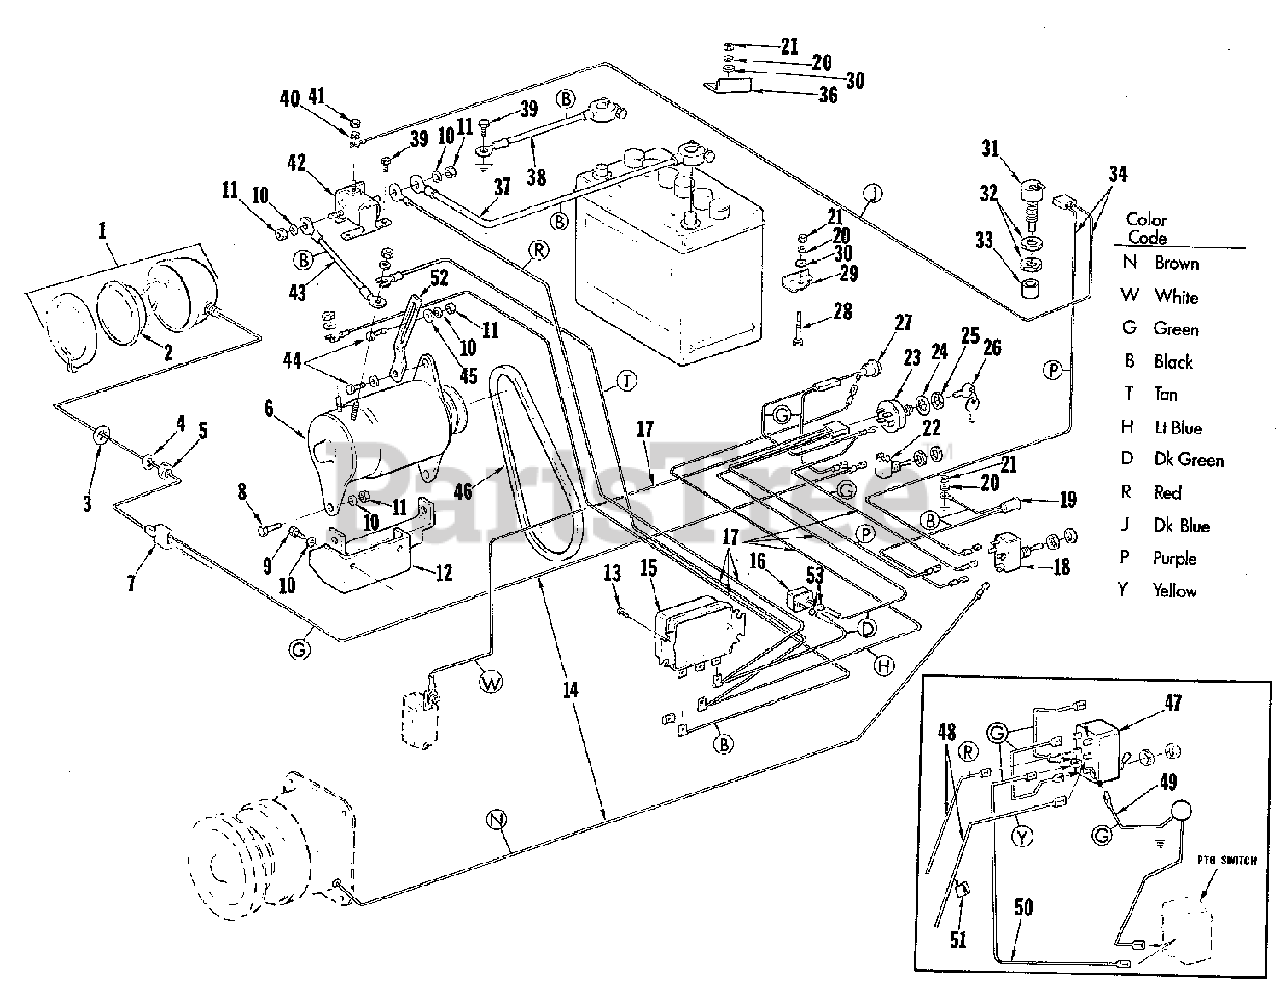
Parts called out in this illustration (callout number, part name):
1	LAMP ASSEMBLY
3	WASHER, Flat, 7/16
4	WASHER, Lock, 1/2
5	NUT, Hex Fin, 1/2-13
6	MOTOR, Generator
7	CONNECTOR, Insulated
8	SCREW, Hex Head Cap, 5/16-18 x 1-1/4
9	SCREW, Hex Head Cap, 5/16-18 x 3/4
10	WASHER, Lock, Regular, 5/16
11	NUT, Hex Fin, 5/16-18
12	SUPPORT ASSEMBLY, Generator
13	SCREW, Tapping (Taptite) 1/4-20 x 5/8
14	HARNESS ASSEMBLY, Light & PTO
15	REGULATOR, Voltage
16	BREAKER, Circuit
17	HARNESS ASSEMBLY, Wiring
18	SWITCH TOGGLE, PTO
19	LIGHT, Pilot
20	WASHER, Lock, 1/4
21	NUT, Hex, 1/4-20
22	SWITCH, Light Toggle
26	KEY, Set (Ignition)
27	INDICATOR, Lamp Assembly
28	SCREW, Hex Head Cap, 1/4-20 x 2
29	CLAMP, Battery (L.H.)
31	SWITCH, Safety
32	NUT, Hex Special
33	BOOT, Rubber
34	WIRE ASSEMBLY, Switch
36	CLAMP, Battery (R.H.)
37	CABLE, Battery to Solenoid
38	CABLE, Battery to Ground
39	SCREW, Taptite, 1/4-20 x 1/2
40	WASHER, Lock, Extension Tooth #10
41	NUT, Machine Screw Hex, 10-32
43	CABLE, Generator to Solenoid
44	SCREW, Hex Head Cap, 5/16-18 x 3/4
45	WASHER, 5/16
46	BELT, Generator
47	SWITCH, Toggle (Actuator) T-16H
48	HARNESS, Switch to Ground (T-16H)
49	LEAD, Switch to Groun (T-16H)
50	LEAD, Switch to PTO Switch (T16H)
51	CLIP, Speed (T-16H)
52	ARM, Belt Tightener
53	WASHER, Insulation
